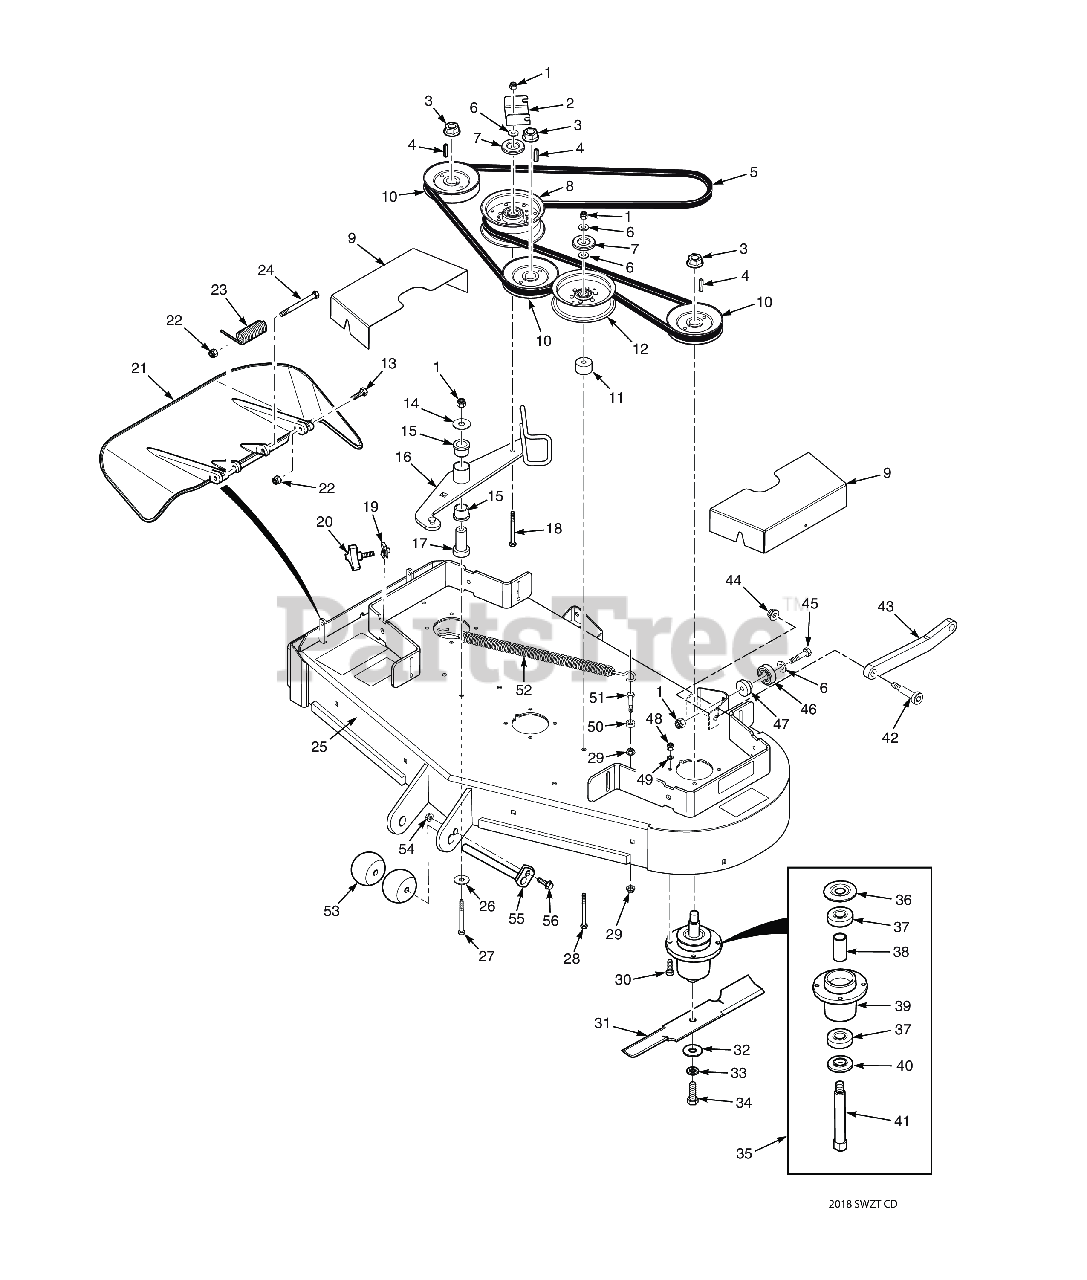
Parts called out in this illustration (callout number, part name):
1	HEX NUT, ELASTIC STOP LOCK, 3/8-16
2	Bracket, Belt Guide
3	Nut, 3/4-16 Spriral Lock
4	Key, 1/4 x 1/4 x 1.25" Pulley Mtg.
5	Belt, Cutter Deck
6	Flatwasher, 3/8 (.391 x .938 x .105 HD) Grade 8
7	Quick Pin, 5/16" Dia.
8	Pulley, Idler 5" Dia.
9	Belt Cover
10	Pulley, 5.13" OD - 25mm Bore
11	Spacer, Idler Pulley
12	Pulley, 5" Idler
13	Bolt, Hex Head 5/16-18 x 1-1/2" - Front
14	Flatwasher, 3/8-.406 x 1-1-1/2 x 7 Gauge
15	Bearing, Plastic
16	Idler Arm Assembly
17	Pivot, Idler
18	Capscrew, Hex Head 3/8-16 x 3.25"
19	U-Nut, 3/8-16
20	Knob, w/stud 3/8-16 x 1-1/4"
21	Discharge Chute Assy. SFZ48
22	HEX NUT, ELASTIC STOP LOCK, 5/16-18
23	Spring, Discharge Chute
24	Bolt, 5/16-18 x 4-3/4" Hex Head
25	Cutter Deck w/Decals, SMWZT-48
26	Flatwasher, 3/8-.406 x 2.25" x .1875
27	Capscrew, Hex Head 3/8-16 x 3-3/4"
28	Bolt, Hex Head, 3/8-16 x 3-1/2"
29	NUT, 3/8-16 SERRATED FLANGE HEX HEAD
30	Bolt, Hex Head 5/16-18 x 1-1/2" Grade 8
31	Cutter Blade, 16-1/2" (48V)
32	Flatwasher, 5/8-.688 x 1-3/4 x .134 HD
33	Lockwasher, 5/8" Spring
34	Bolt, Hex Head 5/8-11 x 1-1/2"
35	Spindle Assembly
36	Debris Shield
37	Bearing
38	Spacer, Bearing
39	Spindle Housing Assembly
40	Protector, Bearing
41	Shaft, Spindle
42	Bolt, Shoulder 1/2 x 3/8-16 x 2-3/4"
43	Pusharm
44	Nut, Flange Elastic Stop Nut, 3/8-16
45	Bolt, Hex Head 3/8-16 x 1-3/4" (Kohler EFI)
46	Bearing
47	Spacer, Bearing
48	Lock Nut, 5/16-18 Elastic Stop Grade 8
49	Lockwasher, 5/16 (.317 x .586 x .078) Helical Spring
50	SPACER, IDLER
51	Bolt, Hex Head 3/8-16 x 1-1/2" Grade 8 Black
52	Spring, Cutter Deck Idler
53	Wheel, Anti-Scalp
54	Nut, Serrated Flange 5/16-18 (Right Front Engine Mounting, Briggs and Kohler Only)
55	Shaft Weldment, Guide Roller
56	Bolt, Heax Head 5/16-18 x 1" (48V / 52V)
